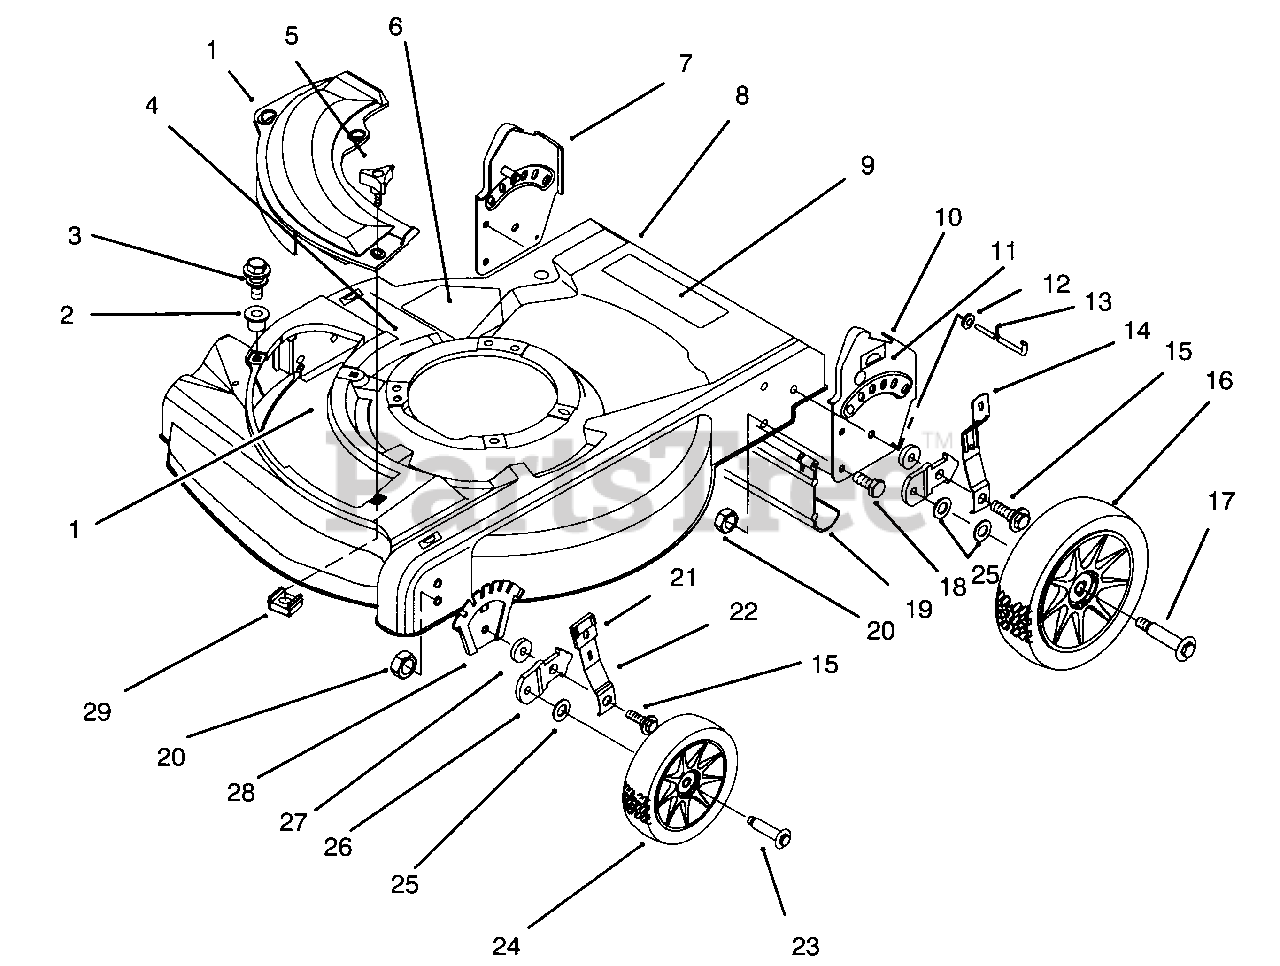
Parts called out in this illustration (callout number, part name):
1	Plate-Cover, Mulch
2	Grommet-Plastic
3	Screw-Thread Forming
4	Decal-Danger
5	Knob
6	Decal-Danger
7	Handle Bracket Ass'y-RH
8	Housing & Baffle Ass'y (Incl. Ref. #4, 6, & 11)
9	Decal-Danger
10	Handle Bracket Ass'y-LH
11	Decal-H.O.C. L.H.
13	Rod-Trailing Shield
14	Spring Arm Assembly
15	Bolt-Shoulder
16	Wheel Ass'y-8"
17	Bolt-Wheel
19	Shield-Trailing
21	Knob-H.O.C. Lever
22	Arm-Spring, Front
23	Bolt-Wheel
24	Wheel Ass'y-6"
25	Washer-Wheel Bolt
26	Bracket-H.O.C.
28	Plate-H.O.C. Front
29	Nut-Cage
